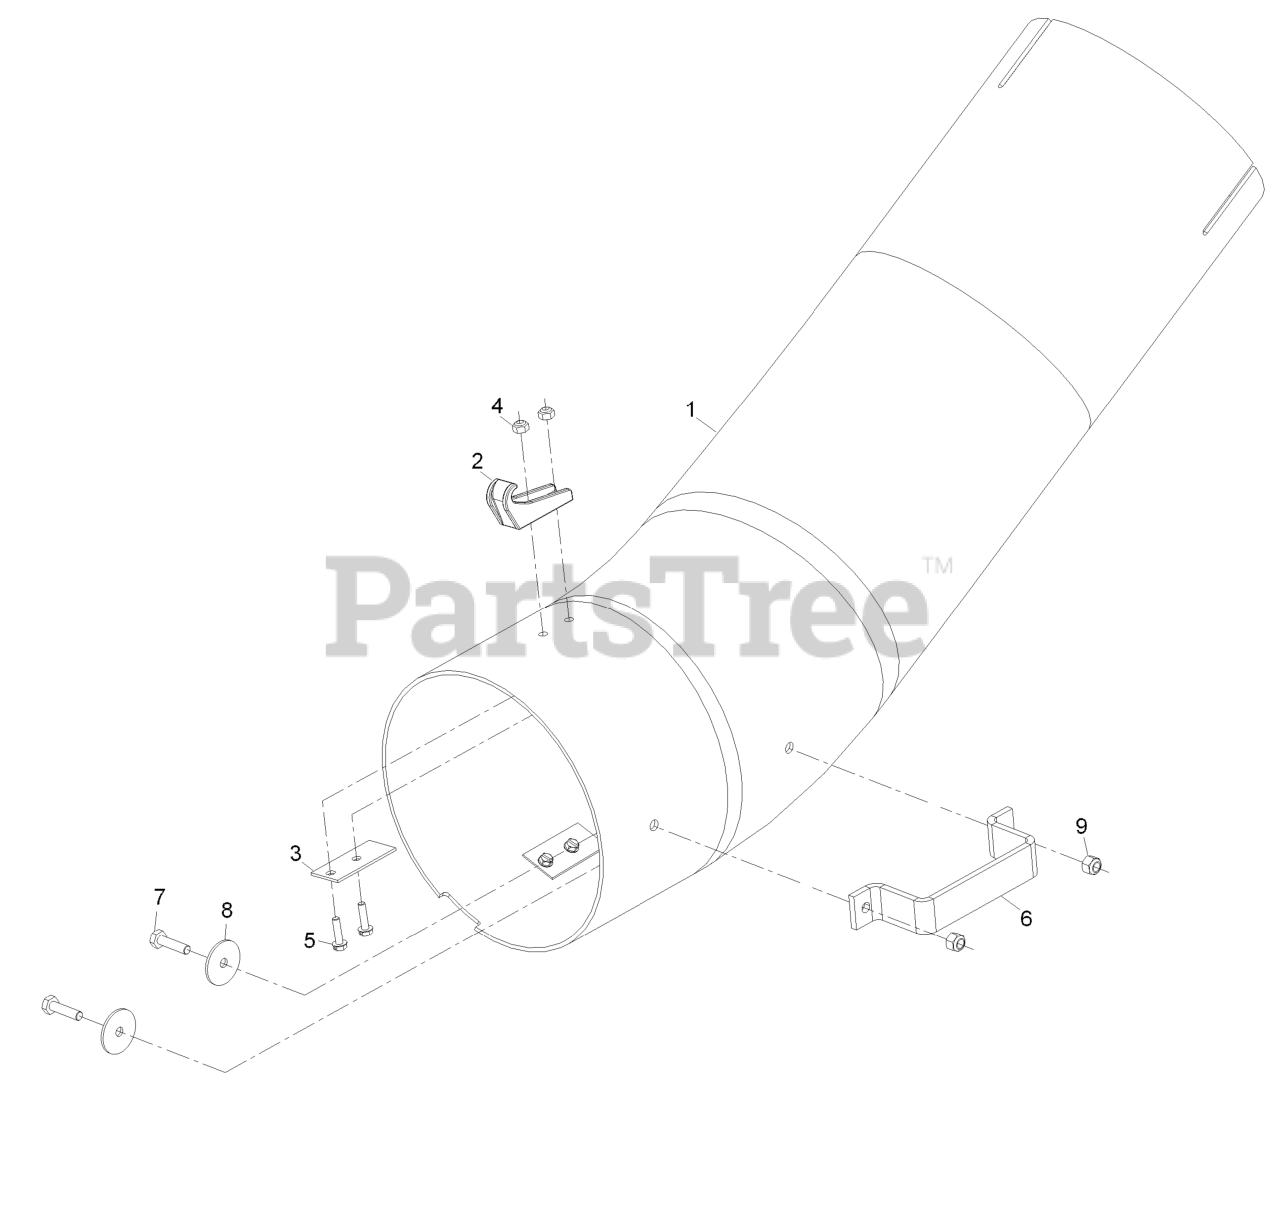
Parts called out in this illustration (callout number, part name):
2	Latch-Catch
3	Plate-Backing
4	Tube, Lower
5	Screw-HH 1/4-20 X 1
7	Nut-Nyloc #10-24
8	Nut-Nyloc 1/4-20
9	Screw-HWH #10-24 X 3/4
